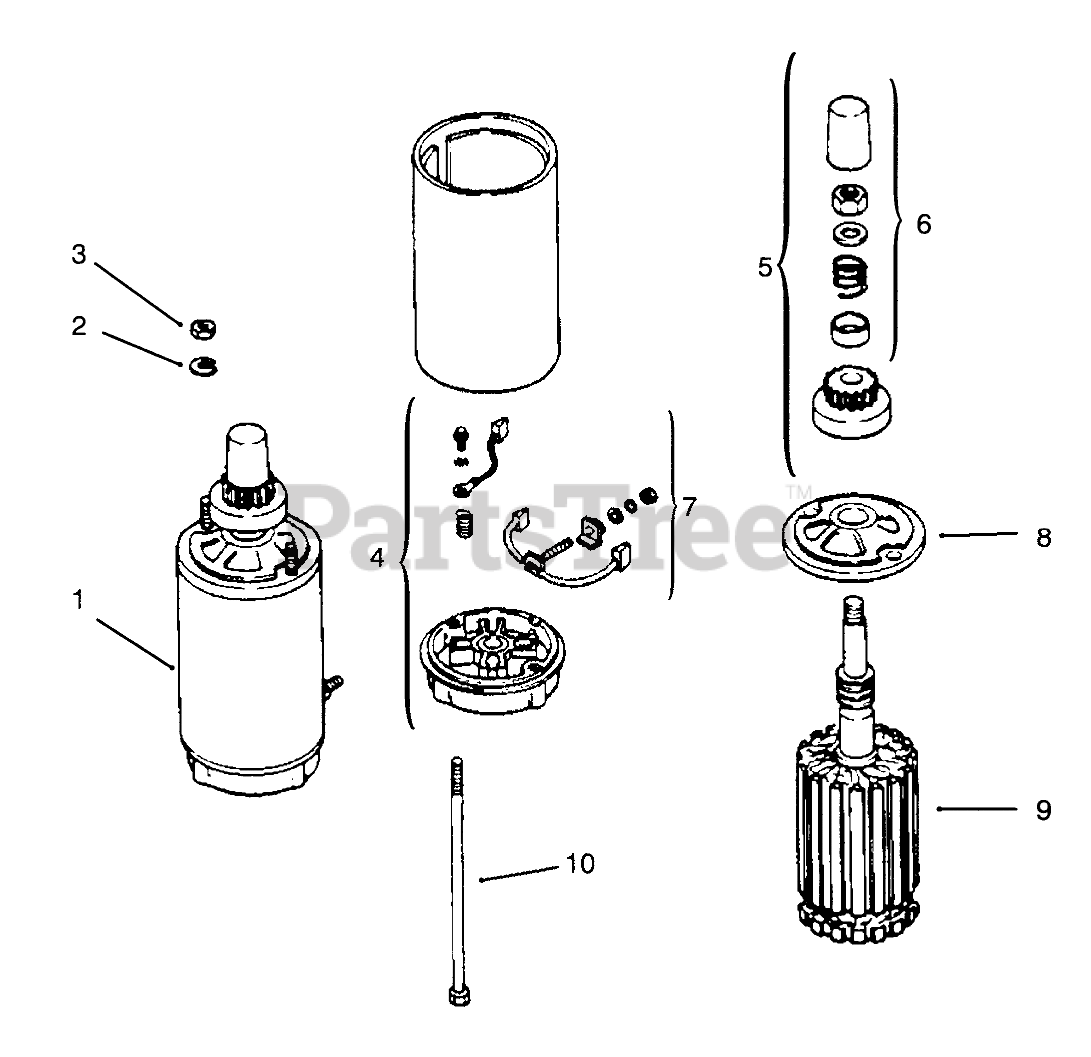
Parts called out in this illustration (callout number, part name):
1	Starter Assembly (Incl. Ref. #4-10)
2	Washer
4	Cap-Commutator End (Incl. Ref. # 9)
5	Kit-Drive (Incl. Ref. #5)
6	Kit-Drive Parts
7	Kit-Brush
8	Cap-Drive End
9	Armature
10	Bolt
